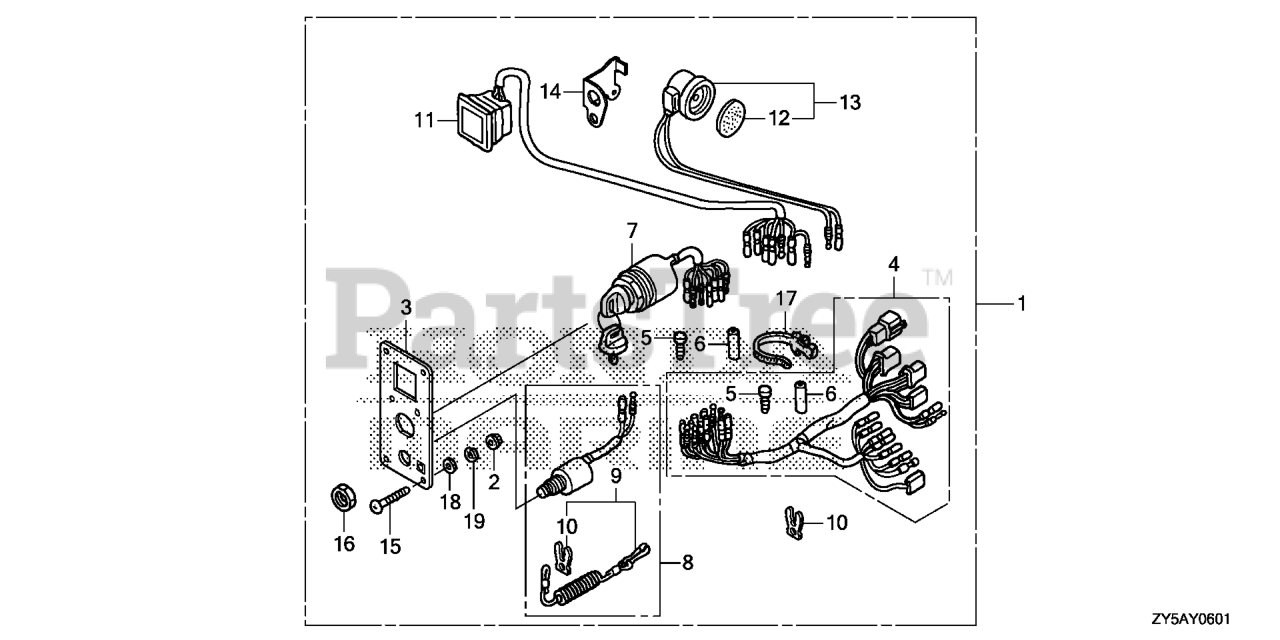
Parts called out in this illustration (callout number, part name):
1	PANEL KIT, SWITCH (4-LED)
2	NUT, FLANGE (5MM) DUAL QTY = (8) (SINGLE)
2	NUT, FLANGE (5MM)
3	PANEL, CONTROL
4	HARNESS ASSY., SWITCH PANEL
5	PLUG, CONNECTOR (INNER) (TROLLING CONTROL)
6	PLUG, CONNECTOR (OUTER) (ENGINE NO.)
7	SWITCH ASSY., COMBINATION (SINGLE) (DUAL)
8	SWITCH ASSY., EMERGENCY STOP
9	WIRE, EMERGENCY (SINGLE) (DUAL)
10	CLIP, EMERGENCY LOCK
11	LAMP ASSY., INDICATION (4-LED)
12	PLATE, TURN SIGNAL BUZZER DUAL QTY = (2) (SINGLE)
13	BUZZER, WARNING DUAL QTY = (2) (SINGLE)
14	BRACKET, BUZZER
15	SCREW, PAN (5X40) DUAL QTY = (8) (SINGLE)
16	NUT, HEX. (16MM) DUAL QTY = (2) (SINGLE)
17	BAND, WIRE HARNESS (150MM) (NATURAL) DUAL QTY = (2) (SINGLE)
18	WASHER, PLAIN (5MM)
18	WASHER, PLAIN (5MM) DUAL QTY = (8) (SINGLE)
19	WASHER, SPG (5MM)
19	WASHER, SPRING (5MM) DUAL QTY = (8) (SINGLE)
